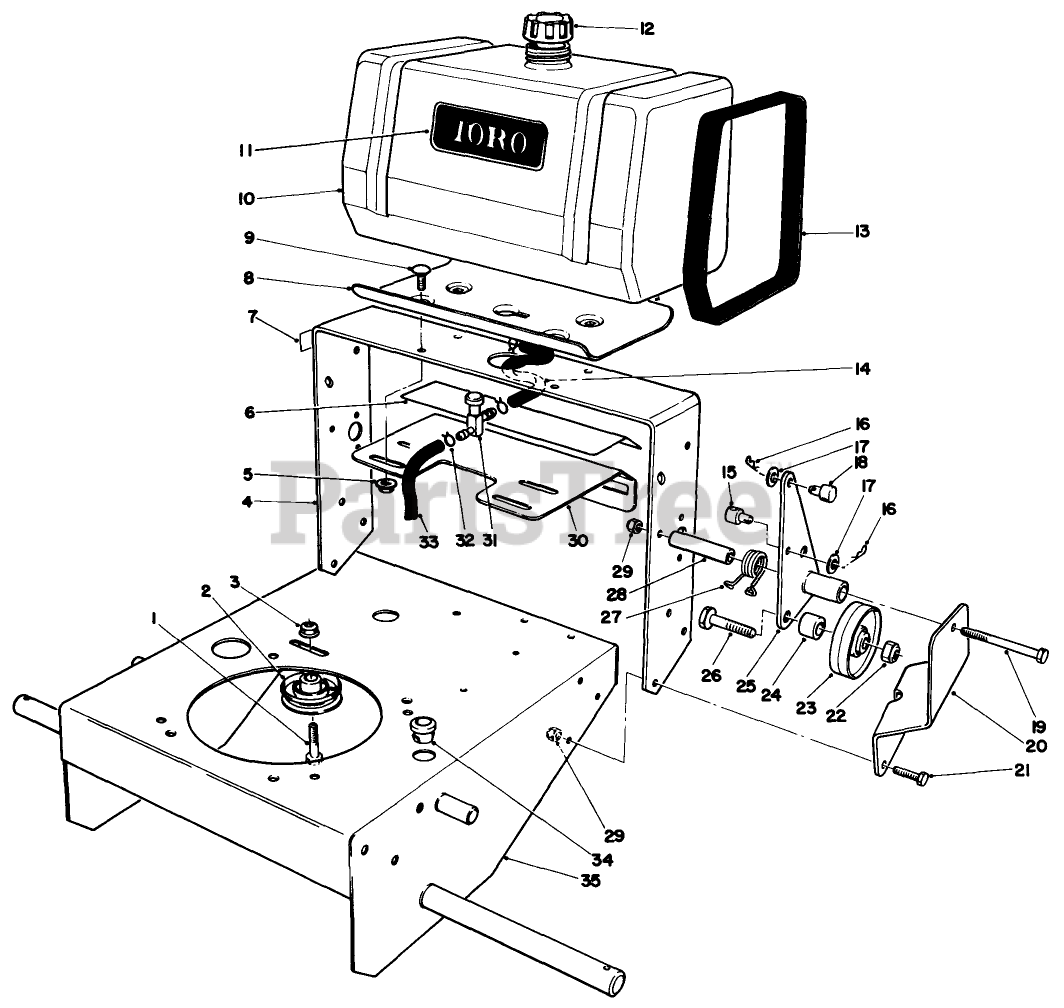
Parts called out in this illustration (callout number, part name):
1	SCREW-HH
2	PULLEY-IDLER
3	NUT-HF
5	NUT-HF
9	BOLT-CARR
12	GAS CAP ASM
15	ROD FITTING
17	WASHER-PLAIN
19	SCREW-HH
21	SCREW-HH
22	NUT-LOCK, NI
24	WHEEL IDLER SPACER
25	LH IDLER BRKT WA
26	SCREW-LEVELER
27	SPRING-TORSION, LH
29	NUT-LOCK, NI
30	CONTROL PLATE *R
34	GROMMET
